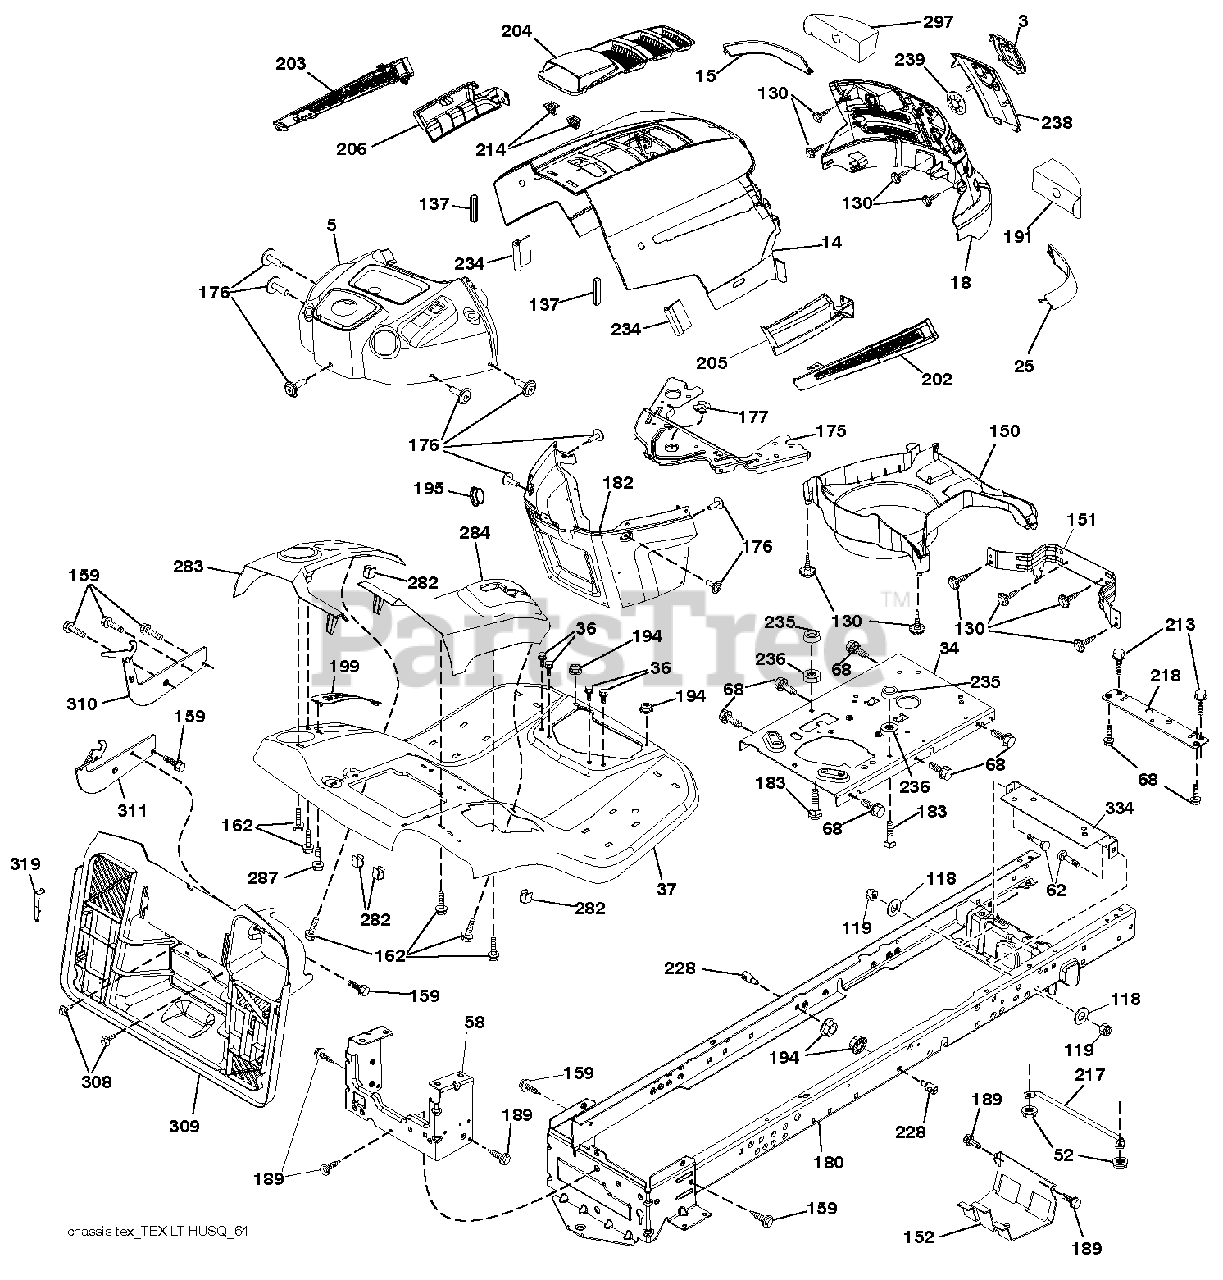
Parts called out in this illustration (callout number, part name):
3	LOGO.HUSQ.GT.LT.CROWN.H
5	SUBASM.DASH.UPPER.W/BUMPER
14	HOOD.HUSQVARNA.LT.ORANGE
15	LENS.HUSQVARNA LT.RH
18	GRILLE.SVC.HUSQVARNA.GREY
25	LENS.HUSQVARNA LT.RH
34	PLATE.ENGINE.10GA.CRD.GENII
36	SCREW 5/16"
37	FENDER.TEX.SRD.CRD.BASE
52	LOCKNUT
58	DRAWBAR UPPER 2PC SMALL FENDER
62	BOLT D
68	SCREW LT
118	WASHER
130	SCREW.#10 X 0.750.BOS
137	BUMPER DASH
151	BRACKET PIVOT
152	SHIELD.BROWNING.W/TEX
159	SCREW, 3/8-16X3/4
162	SCREW.HI-LO.CONSOLE
175	CROSSMEMBER
176	SCREW.#10-24X5/8.RN.QU
177	BUSHING STEERING
180	CHASSIS.WLDMNT.14GA.2PC.18".TI
182	DASH.LOWER.PREDATOR LT
183	BOLT.5/16-18X1-1/4 FULL THD
189	SCREW
191	INSERT.REFLECTIVE.RH.
194	NUT LOCK HEX FLANGE 5/16-18
195	PLUG.TEX.DASH.SVC.MINDER.GREY
199	PLATE DECK LIFT
202	VENT.SIDE.HUSQVARNA.LT.RT
203	VENT.SIDE.HUSQVARNA.LT.LFT
204	SUBASM.TOP.VENT.HUSQ.LT
205	SKIRT.SIDE.HUSQVARNA.LT.RT
206	SKIRT.SIDE.HUSQVARNA.LT.LEFT
213	BOLT
214	CLIP.RETAINER.TINNER.
217	ROD.PIVOT.HOOD
218	X-PIECE.HOOD.STOP.NON/
228	STUD.FASTNER.W/ANTI-ROTATE
234	BUMPER.HOOD.TEX.HUSQVARNA
235	SPACER FENDER
236	NUT.CENTERLOCK.5/16-
238	TRIM.HUSQ LT.668
282	CLIP.RETAINER.CONSOLE.LT.HUSQ
283	CONSL.DECKLIFT.LH.SRD.TEX.CRD
284	CONSL.SHIFT.GEAR.RH.SRD.GREY
287	SCREW 1/4X20
297	INSERT REFLECTIVE
308	BOLT, 5/16-18 X 1 3/4
309	BACKPLATE.BAGGER.V2.SRD
310	LH.ADJUST.HANGER.BRACKET.ASM
311	RH.ADJUST.HANGER.BRACKET.ASM
319	BRACKET.ACTUATOR.BAGGER.SRD
334	BRACKET.ENGINE
